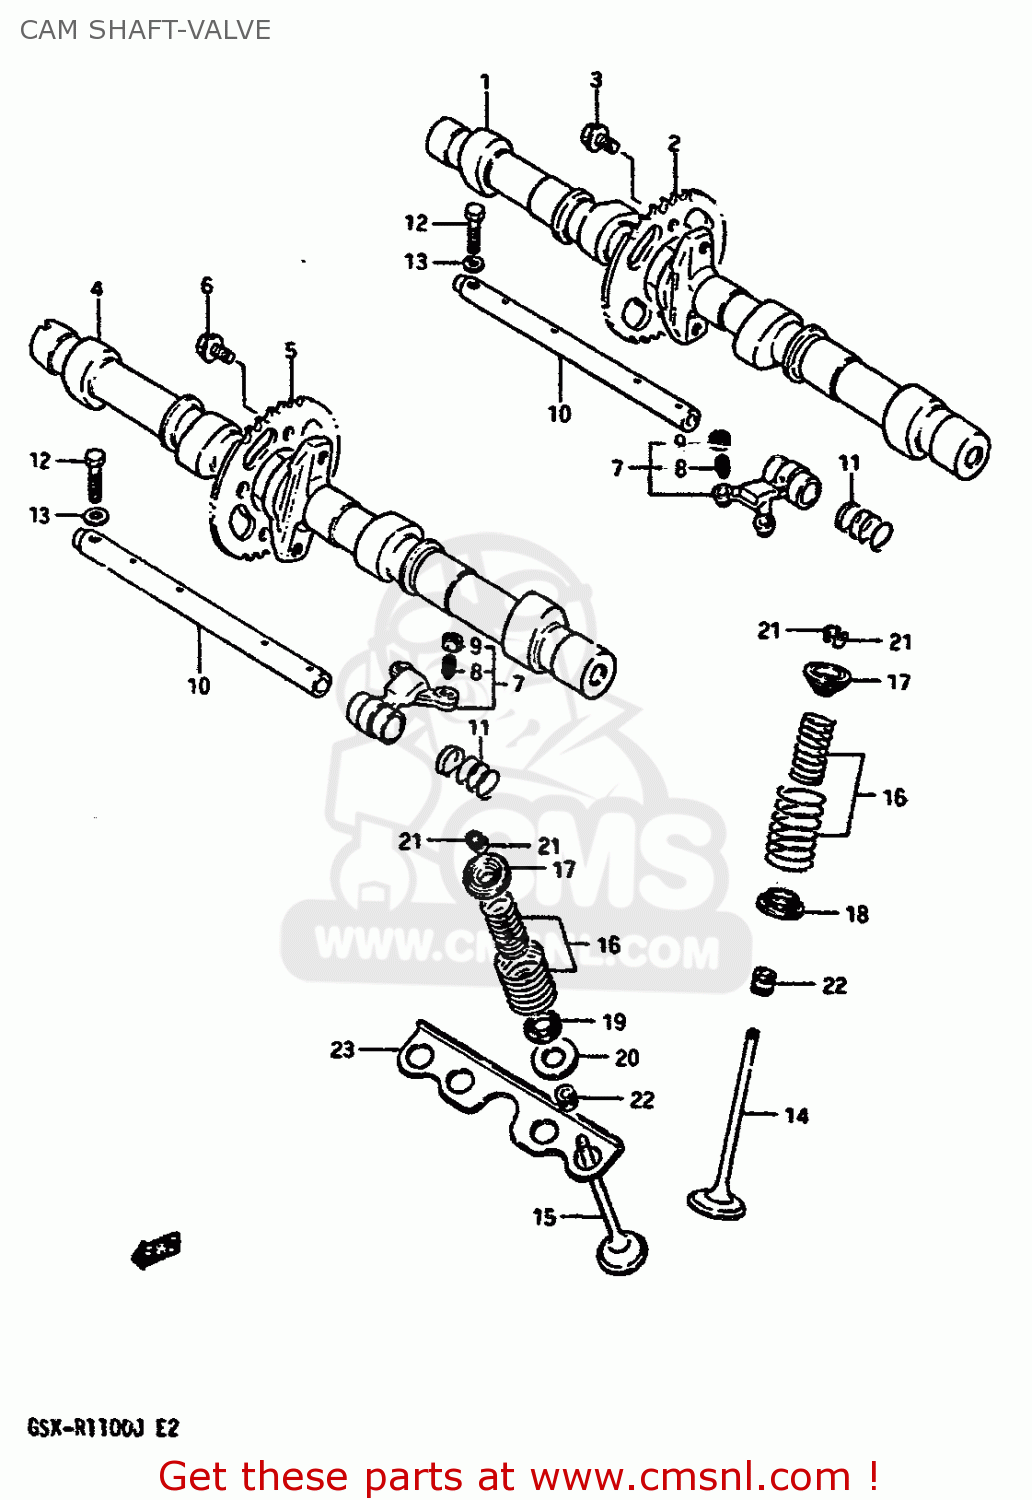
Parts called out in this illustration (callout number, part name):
1	CAMSHAFT
2	SPROCKET,CAMSHAFT
3	BOLT(7X11)
4	CAMSHAFT,EXHAUST
5	SPROCKET,CAMSHAFT
6	BOLT(7X11)
7	ARM,VALVE ROCKER
8	SCREW,TAPPET ADJUSTING
9	NUT,ADJUSTING
10	SHAFT,VALVE ROCKER ARM
11	SPRING
12	BOLT
13	WASHER, LOWER
14	VALVE,INTAKE
15	VALVE,EXHAUST
16	SPRING SET,VALVE
17	RETAINER,VALVE SPRING
18	SEAT,VALVE SPRING
19	SEAT,VALVE SPRING
20	SEAT,VALVE SPRING EXH OUTER
21	COTTER VALVE
22	SEAL,OIL(5X10X9.7)
23	PLATE
